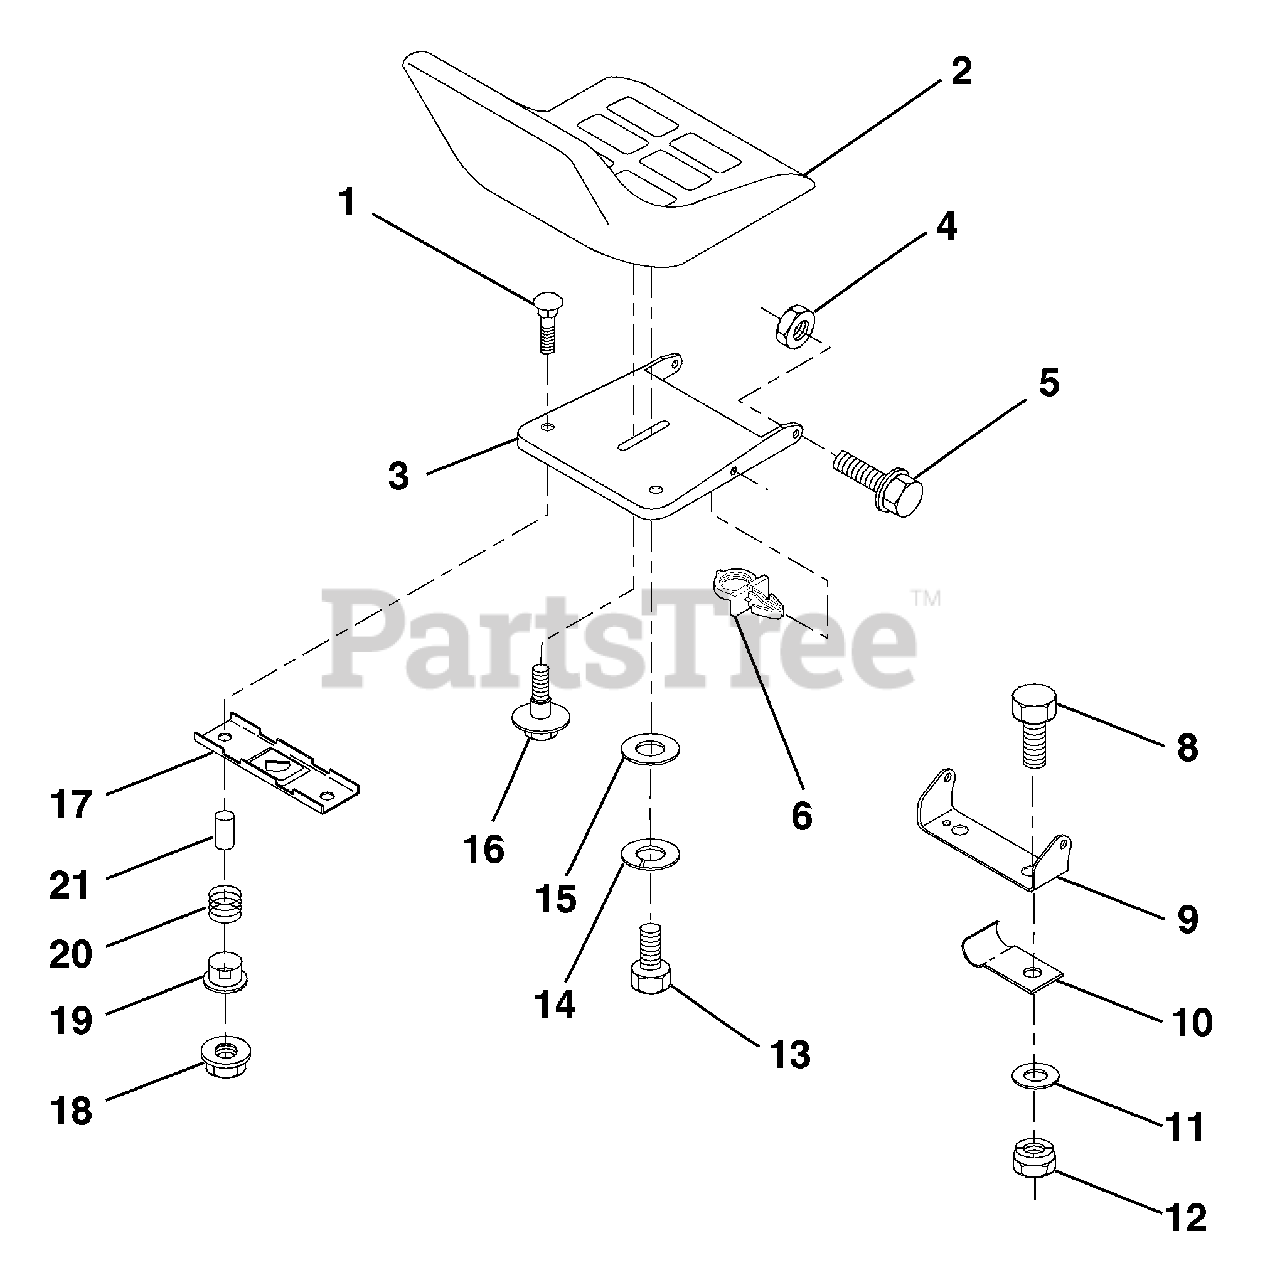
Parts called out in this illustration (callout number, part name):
1	Bolt, Carriage 1/4-20 x 1-3/8
3	Pan, Seat
4	Locknut, Hex w/Ins 5/16-18
5	Bolt, Shoulder 5/16-18 UNC
6	Clip, Push-in
8	Bolt, Fin Hex 3/8-16 UNC x 1
9	Bracket, Pivot Seat
10	Clip, Insulated
11	Washer 12/32 x 2 x 10 Ga.
12	Nut, Lock Hex w/Wsh 3/8-16
13	Bolt Hex 1/2-13 x 7/8
14	Washer Lock Hvy. Hlicl Spring 1/2
15	Washer, 17/32 x 1-3/16 x 12 Ga.
16	Bolt, Shoulder
17	Bracket, Switch, Mounting
18	Nut, Hex Large Flange Lock
19	Bushing, Snap
20	Spring, Compression
21	Spacer, Split 28 Id. x .88 Lg.
